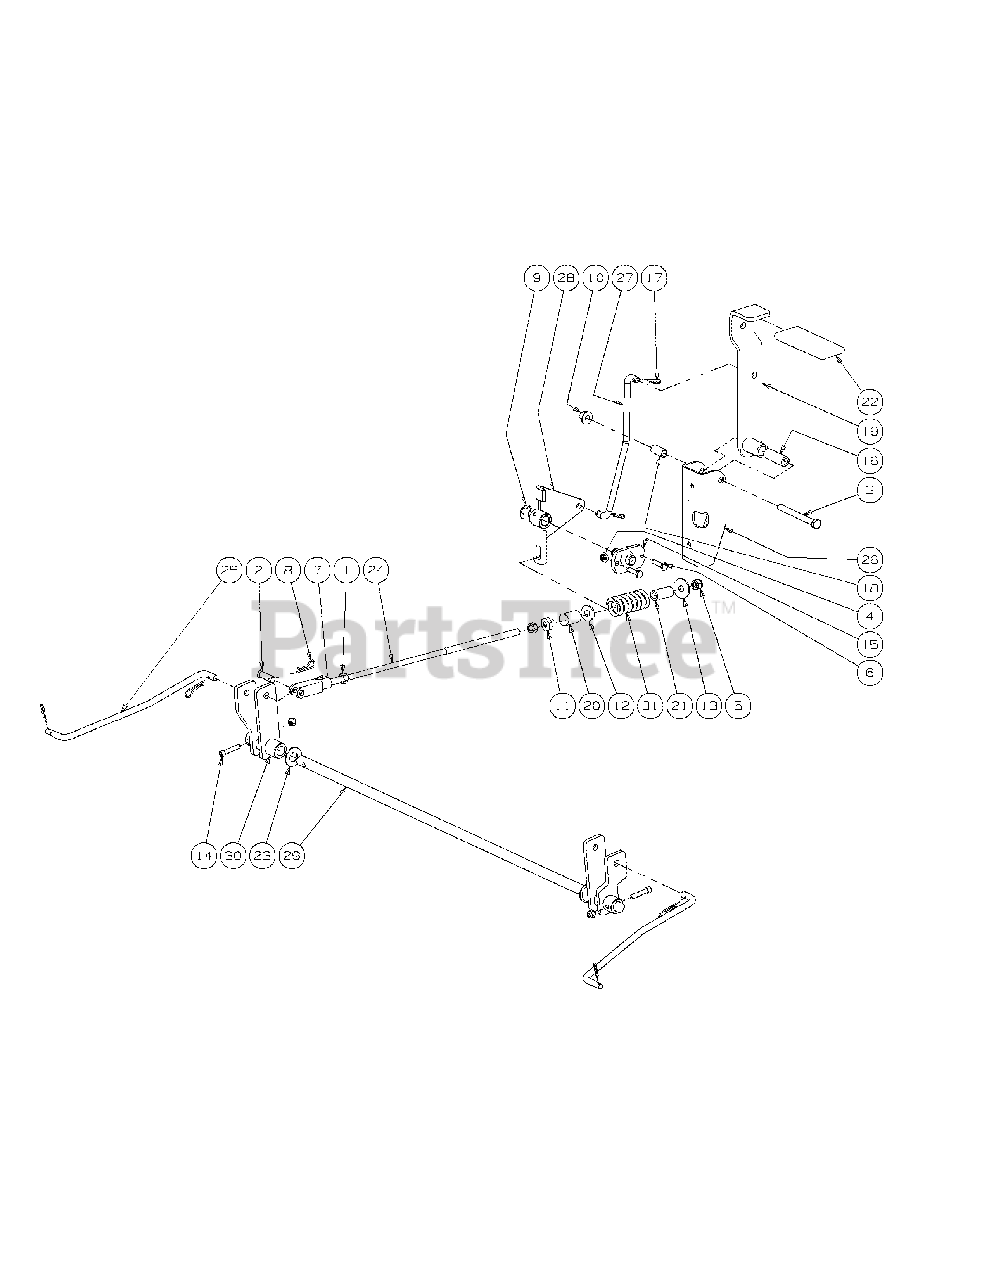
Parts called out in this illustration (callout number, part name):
1	Hex Nut, 3/8-16
2	Clevis Pin, 3/8 x 1-1/8
3	Hex Cap Screw, 3/8-16 x 3-1/2
4	Lock Nut w/Nylon Insert
5	Nylock Nut, 3/8-16
6	Hex Cap Screw, 1/4-20 x 1.00
7	Yoke, 3/8-16
8	Hair Pin, 3/8" - 1/2"
9	E-Ring, 5/8" #5113-62
10	Flange Lock Hex Nut, 3/8-16
11	Shoulder Nut
12	Flat Washer, .406 ID x 1.0 OD x .105
13	Flat Washer, .411 x 1.25 x .100
14	Socket Screw, 1/4-20 x 1.25
15	Bellecrank Pivot, Weldment
16	Spacer, .39ID x .63OD x 1.75LG
17	Cotter Pin, .072 x 1.12 Lg
18	Spacer, .375 ID x .50 x 1.02 Lg
19	Brake Handle
20	Neutral Brake Spring
21	Center Brake Hose
22	Parking Brake Grip
23	Flat Washer, 5/8
24	Connector Rod, 3/8 OD x 16.88 Lg
25	Rear Brake Linkage Rod
26	Parking Brake Mounting Bracket
27	Park Brake Handle Rod
28	Park Brake Bellcrank
29	Park Brake Shaft
30	Rear Brake Arm Assmebly
31	Force Brake Spring
